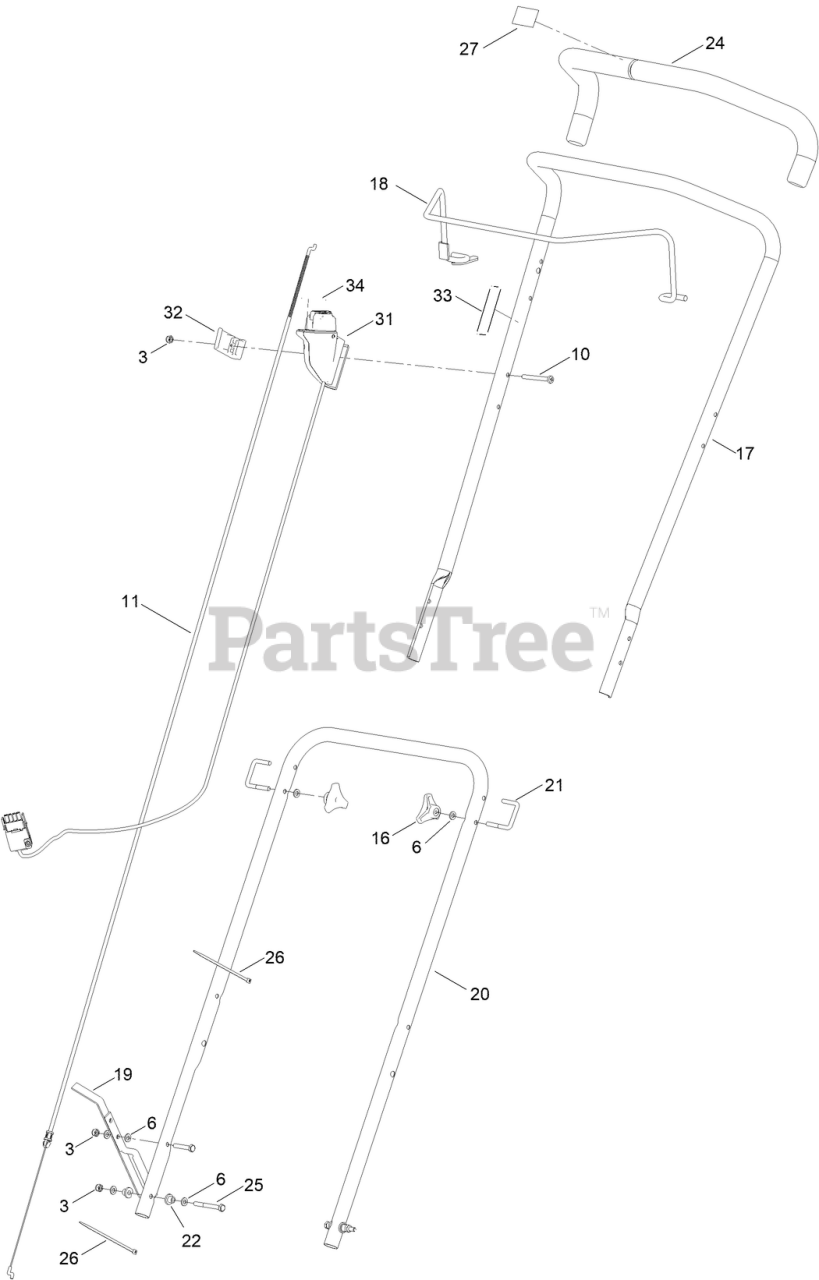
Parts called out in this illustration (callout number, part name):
3	NUT-NYLOC
6	WASHER-PLAIN
10	SETSCREW
11	OPC CABLE
16	HANDWHEEL
17	HANDLE-UPPER
18	ARM-BAIL
19	FOOTSTOP
20	HANDLE-LOWER
21	BOLT-U
22	SPACER-HANDLE
24	GRIP-HANDLE
25	BOLT-HEX
26	TIE-CABLE
27	DECAL-STOP
31	SWITCH-STARTER ASM
32	CLAMP-CABLE
33	DECAL-BUTON, PUSH, 60V
34	DECAL - SPEED CONTROL
